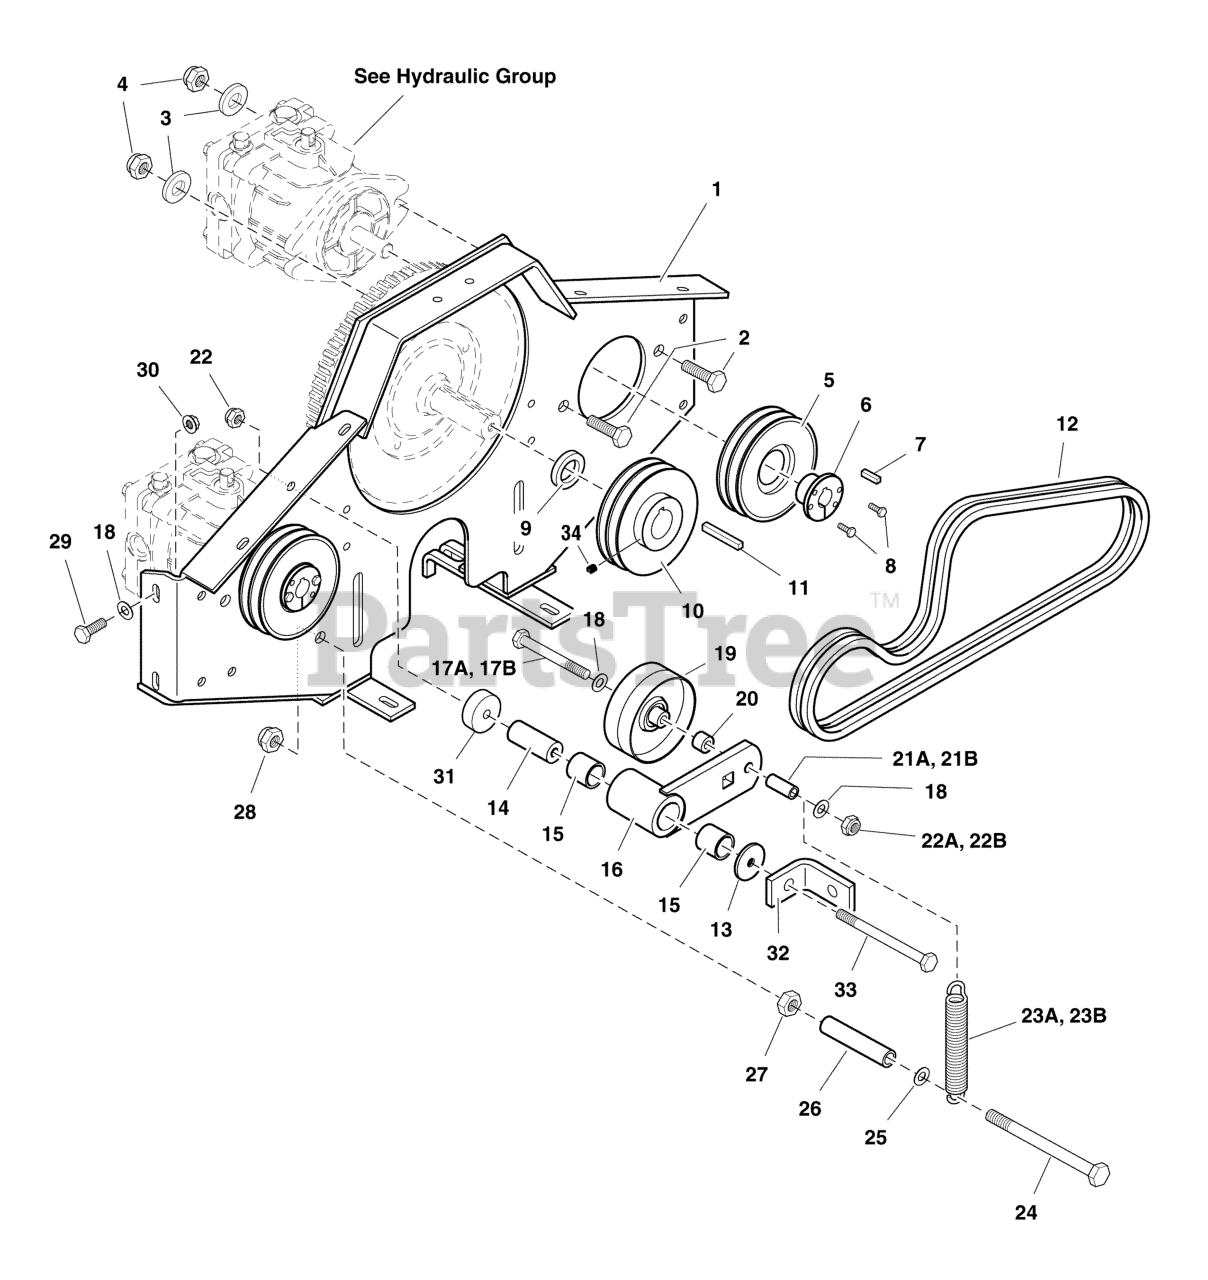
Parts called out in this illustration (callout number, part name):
1	PUMP MOUNT PLATE
2	BOLT, 1/2-20 X 1-3/4" GD8 CZ
3	WASHER, Frame Retaining
4	NUT, Hex, Nylon Lock, 1/2-20
5	PULLEY, Pump Drive
6	HUB, Taper Lock
7	KEY, 5MM SQ. x 25MM w/ Round Ends
8	BOLT, 1/4-20 X 1" GD5 CZ
9	SPACER, 1.13 x 1.75 x .25
10	PULLEY, Crankshaft
11	KEY, 1/4 SQ. x 3
12	BELT, Pump Drive (set of 2)
13	RETAINER, Idler Arm
14	SPACER, .39 X 1.00 X 2.55, SS
15	BUSHING, Brass
16	PUMP DRIVE IDLER ARM
17A	BOLT, 3/8-16 X 4" GD5 CZ
17B	BOLT, 3/8-16 X 3" GD5 CZ
18	WASHER, 3/8 SAE
19	PULLEY, Idler, Flat
20	SPACER, .39 x .75 x .38
21A	SPACER, .38 x .50 x 1.00
21B	SPACER, .38 x .50 x .75
22	NUT, 3/8-16 HEX NYLON LOCK
22A	NUT, 3/8-16 HEX NYLON LOCK
22B	NUT, 3/8-16 Hex Side Lock
23A	SPRING, Extension
23B	SPRING, Extension, Swivel End
24	BOLT, 1/2-13 x 5
25	WASHER, 1/2 SAE
26	HOSE, 3-1/4
27	NUT, 1/2-13 Hex Jam
28	NUT, 1/2-13 HEX NYLON LOCK
29	BOLT, 3/8-16 X 1" GD5 CZ
30	NUT, 3/8-16 Hex Serrated Flange
31	SPACER, 1.13 x 1.75 x .57
32	SPRING ANCHOR
33	BOLT, 3/8-16 X 4" GD5 CZ
33	BOLT, 3/8-16 X 4-1/2" GD5 CZ
34	SET SCREW, 5/16-18 X 3/8, KNURL, W/PATCH
